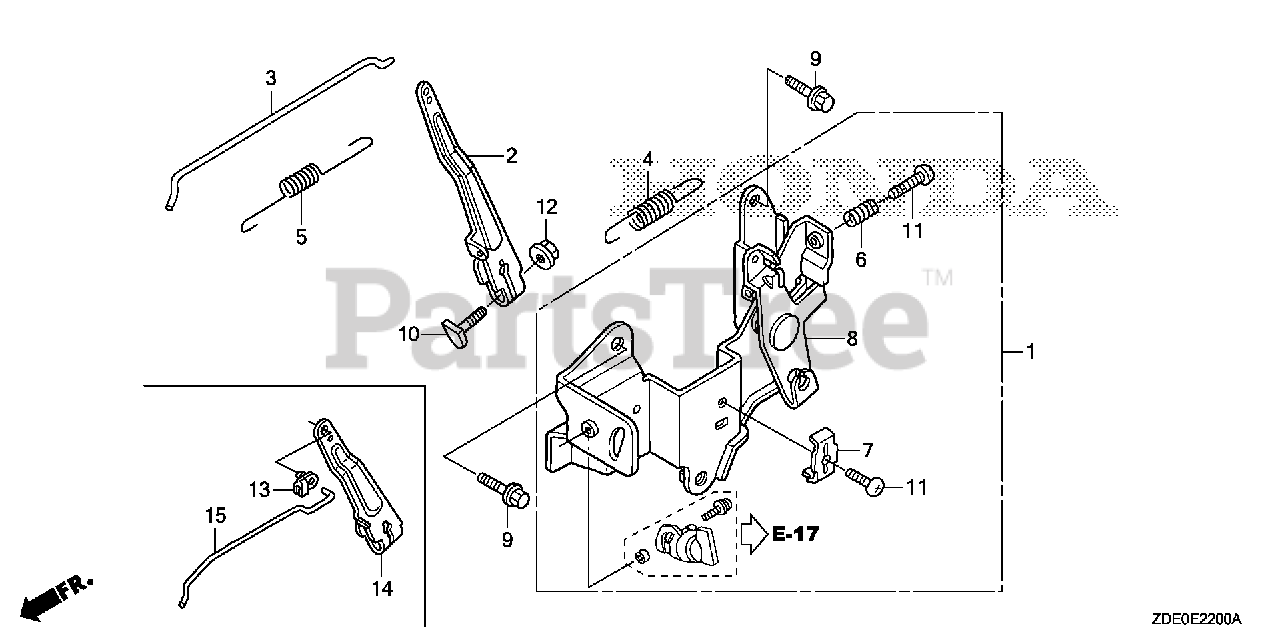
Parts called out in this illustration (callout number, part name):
1	CONTROL ASSY.
4	SPRING, GOVERNOR
5	SPRING, THROTTLE RETURN
6	SPRING, CONTROL ADJUSTING
7	HOLDER, CABLE
8	BASE, CONTROL
9	BOLT, FLANGE (5X12)
10	BOLT, GOVERNOR ARM
11	SCREW, PAN (5X20)
12	NUT, FLANGE (6MM)
13	JOINT, ROD
14	ARM, GOVERNOR
15	ROD, GOVERNOR
